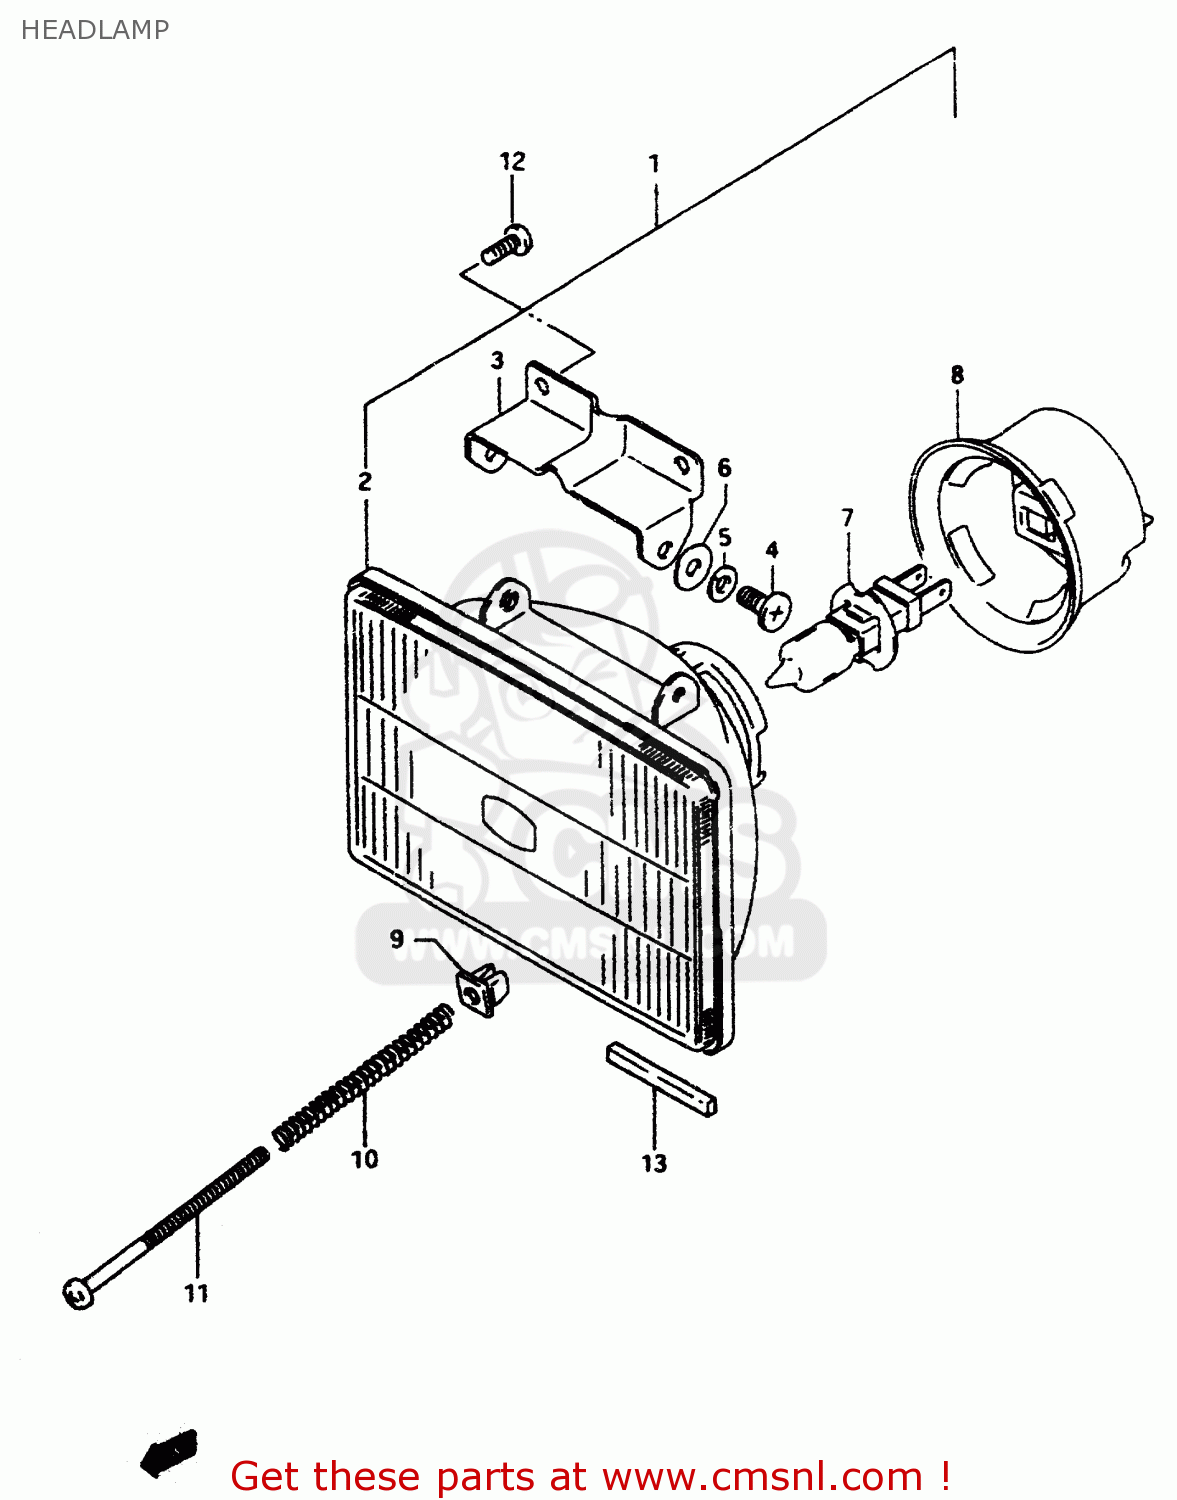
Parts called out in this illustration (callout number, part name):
1	HEADLAMP ASSY
2	UNIT,LAMP
3	BRACKET,LAMP
4	SCREW
5	WASHER,LOCK
6	WASHER
7	BULB(12V55W)
8	COVER,SOCKET
9	NUT,ADJUSTING
10	SPRING,HEAD LAMP ADJUSTER
11	SCREW(4X45)
12	SCREW
13	PROTECTOR(50X50X5)
14	REFLECTOR,REFLEX FR
